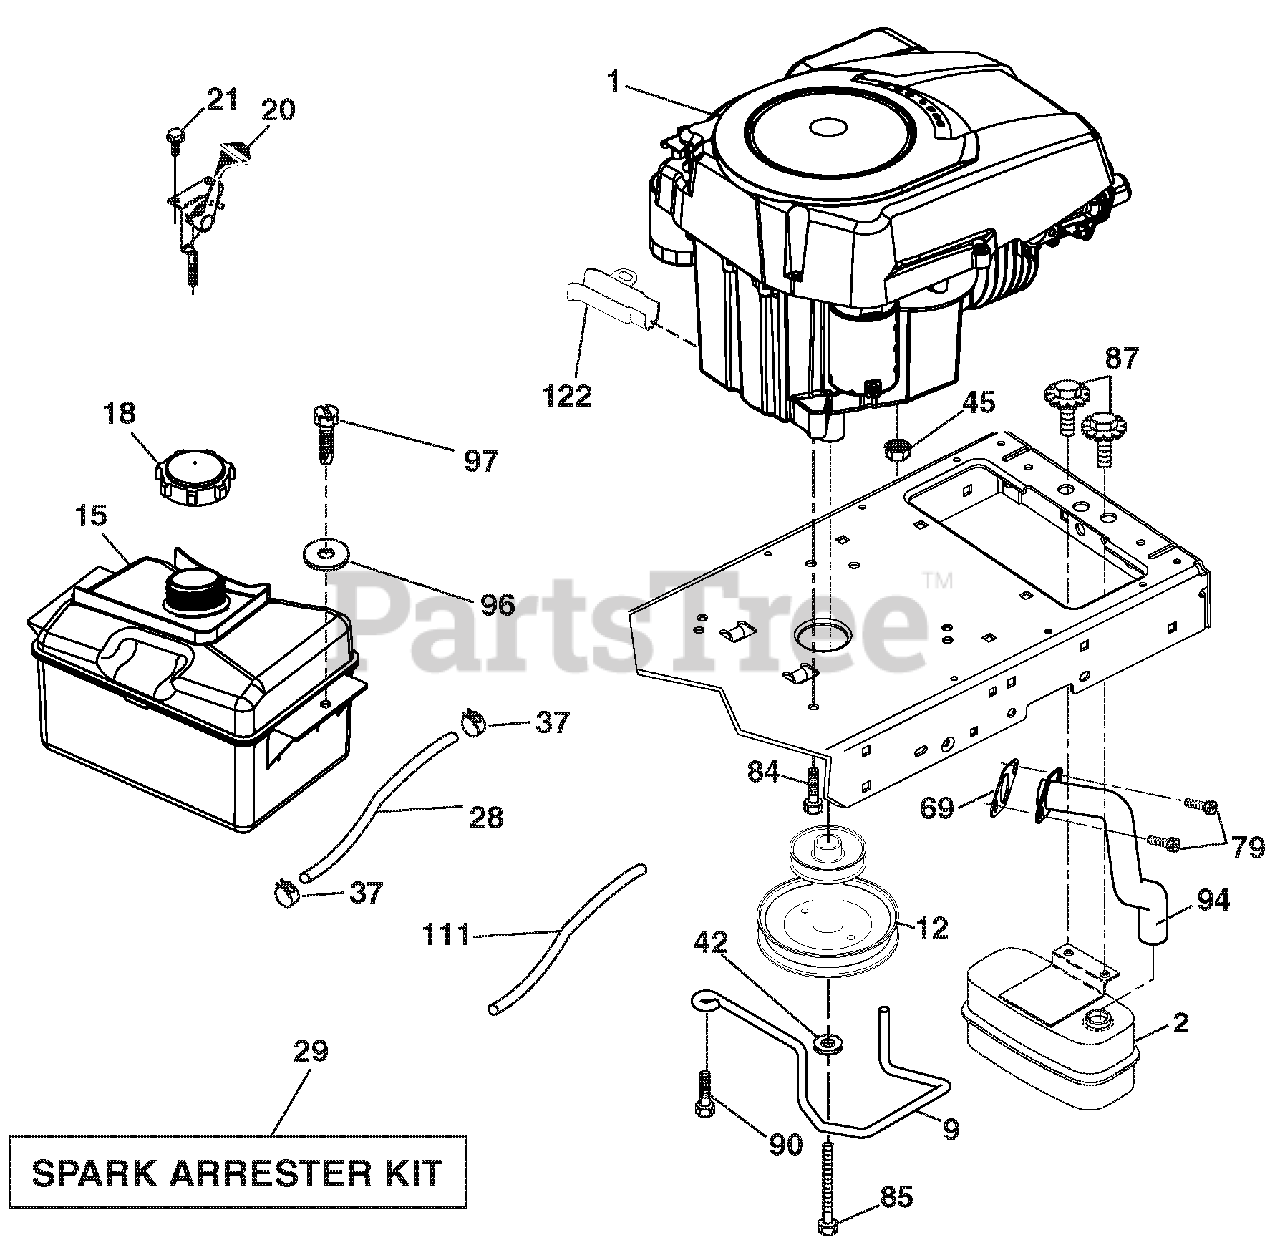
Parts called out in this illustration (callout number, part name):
1	ENGINE KOHL MODEL NO. SV530-3224(581497201)(ORDER PARTS FROM ENGINE MANUFACTURER.)
2	MUFFLER
9	KEEPER BELT ENGINE
12	PULLEY.ENGINE
15	TANK FUEL
18	CAP.FUEL
20	CONTROL THROTTLE/CHOKE
28	LINE.FUEL.22"FRONT.EMIS.CA.LP
29	KIT.SPARK ARRESTOR(392390 B&S)
37	CLAMP.HOSE.BLK.
42	WASHER.LOCK.HVY HLCL.SPR.7/16
45	Nut, Keps Hex 1/4-20 unc
69	GASKET.KOHLER.SV.I.
79	SCREW.SOCKET HD.5/16-18 X .75
84	Screw 3/8-16 x <
85	BOLT.HEX.7/16-20X4XGR5-1.5THR.
87	BOLT.5/16-18UNCX3/4 W/SEMS.BLK
90	SCREW.3/8-16X1.SMGML.TAP/R.BLK
94	TUBE.EXHAUST (ENGINE)
96	WASHER.9/32 X 7/8 X 16GA.
97	SCREW.HEXWSH.THDROL.1/4-20X3/4
111	PURGE.LINE.CARB
122	Extension Drain Oil
